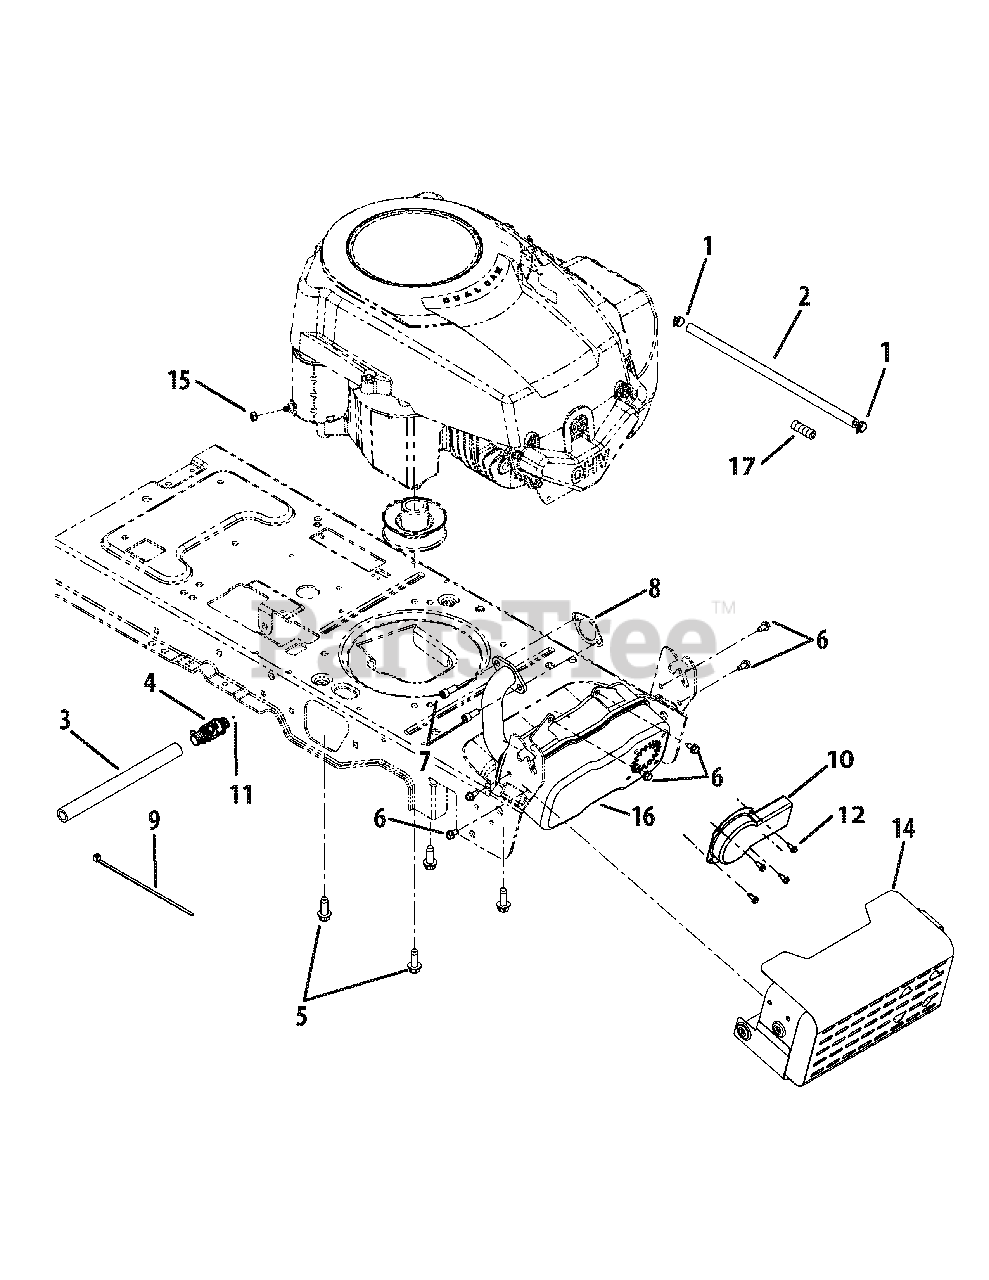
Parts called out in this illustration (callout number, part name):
2	Fuel Line 13" Lg.
3	Oil Drain Hose 9" Lg.
5	TT Screw 3/8-16 x 1.00
6	Hex Wash S-Tapp Screw 1/4-20 x .50
7	Screw. 5/16-18 x .75
10	Long Muffler Deflector
11	Pipe Sealant
12	Hex AB Screw #8-18 x .50
15	Hex Sems Nut 1/4-20
16	Muffler
17	Vent Hose (optional)
